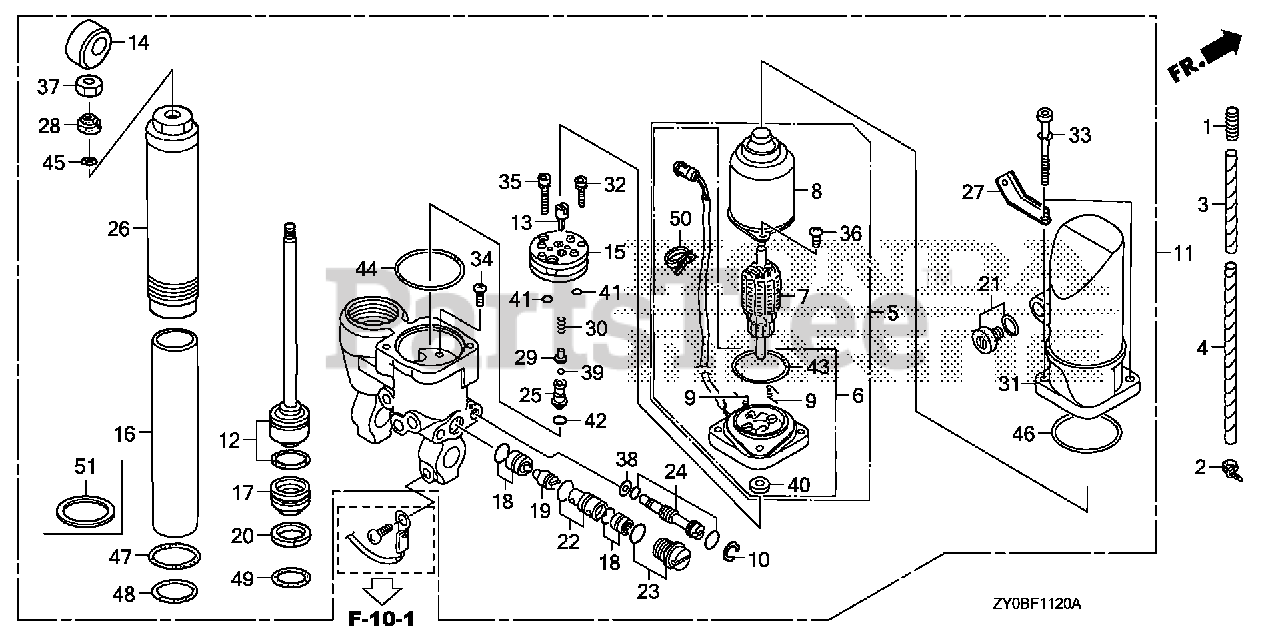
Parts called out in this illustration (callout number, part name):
1	TUBE, CORRUGATE (10MM)
2	BAND (BLACK 3.5X140)
3	TUBE, SPIRAL B
4	TUBE, SPIRAL A
5	MOTOR ASSY., POWER TILT
6	BRACKET ASSY.
9	SPRING, MOTOR
10	CIRCLIP (INNER) (16)
11	TILT ASSY., POWER
12	ROD, PISTON
13	JOINT, DRIVE
14	JOINT, METAL
17	PISTON, FREE
19	SPOOL, VALVE
20	RING, BACK-UP
21	BOLT, PLUG
24	VALVE, MANUAL
25	SEAT C, VALVE
26	TUBE (OUTER)
27	PLATE, SET
28	DUST SEAL
29	GUIDE, SPRING
32	BOLT, HEX.
33	BOLT, HEX.
34	SCREW, PAN
35	BOLT, SOCKET
36	SCREW, PAN (5X0.8)
38	WASHER, SEAL
39	BALL, STEEL
41	O-RING (1.5X6.5)
42	O-RING (1.5X3.5)
44	O-RING (2.0X62.5)
45	O-RING (2.4X12.3)
46	O-RING (2.4X66.6)
47	O-RING (2.0X43.5)
48	O-RING (2.0X34.5)
49	O-RING (2.4X27.7)
50	CLIP, HARNESS BAND (145MM) (BLACK)
51	WASHER, PLAIN
